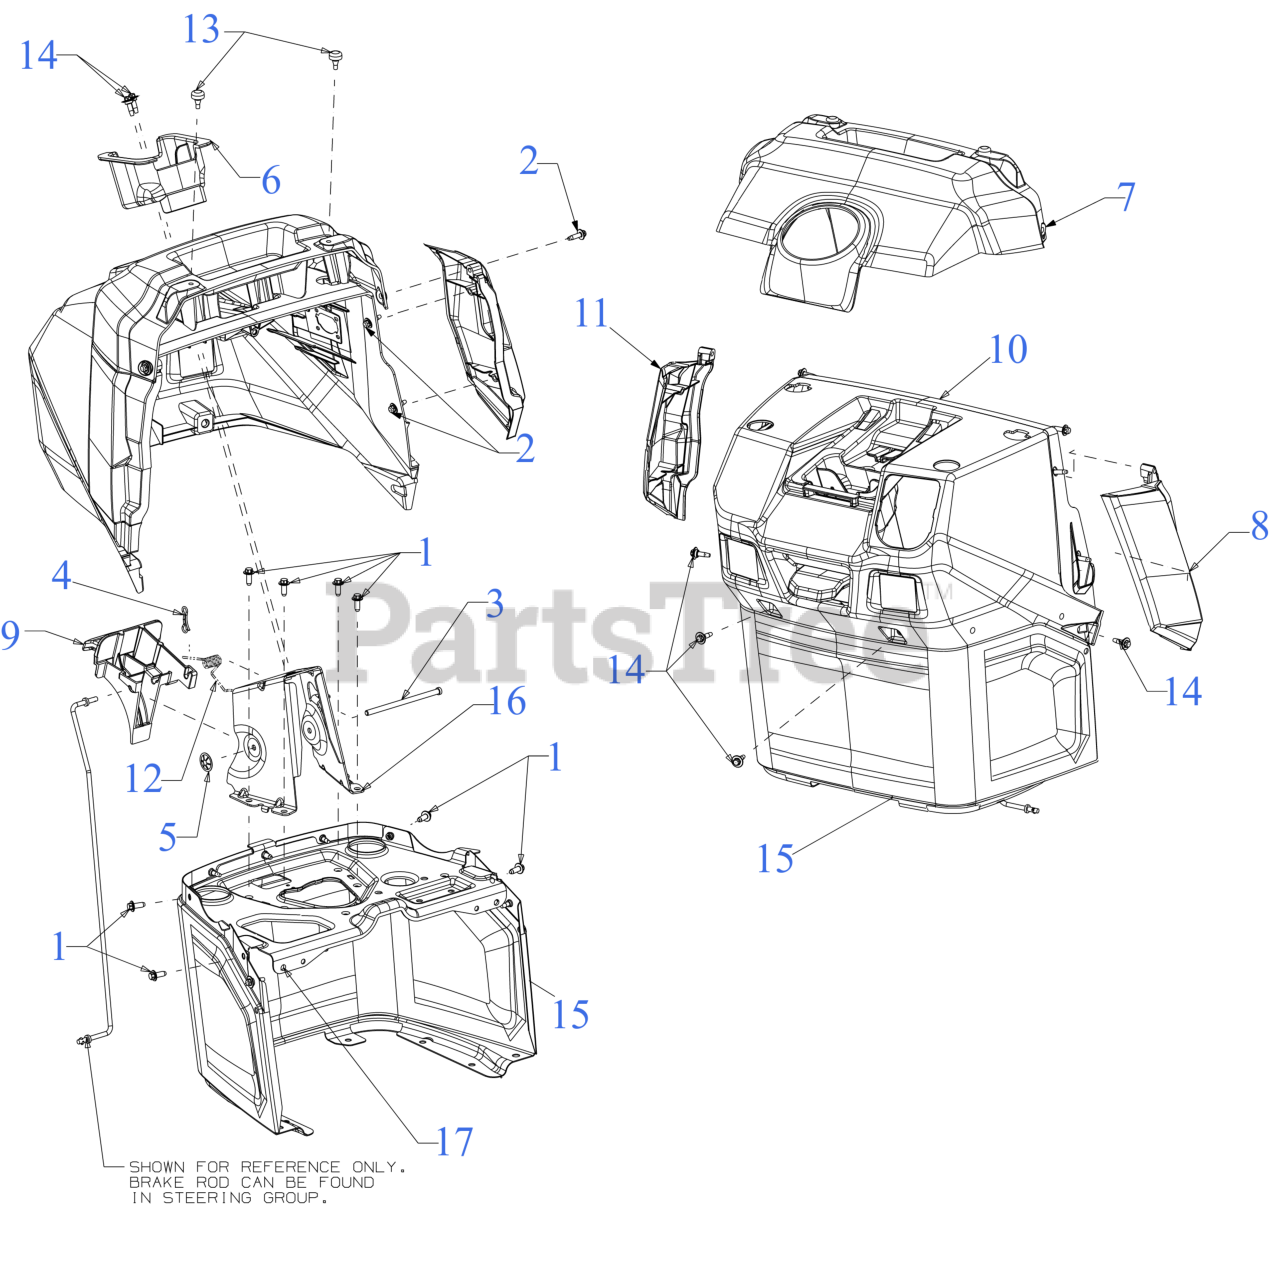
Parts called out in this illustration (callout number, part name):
1	SCREW M6-1 x .625
2	SCREW 1/4-10 x .750
3	HINGE PIN .25 x 4.50
4	BOW TIE COTTER PIN 1/4-5/16
5	PUSH ON NUT
6	STEERING SHAFT BEARING
7	UPPER DASH CAP (CRAFTSMAN)
8	DASH SIDE CAP (RH)
9	BRAKE LEVER
10	DASHBOARD (UPPER) (NO USB)
11	DASHBOARD CAP (LH)
12	TORSION SPRING .330 ID
13	BUMPER, .62 DIA x .3
14	SHOULDER SCREW M6-1 .368 X.115
15	LOWER DASH
17	DASH/FUEL TANK PLATE
